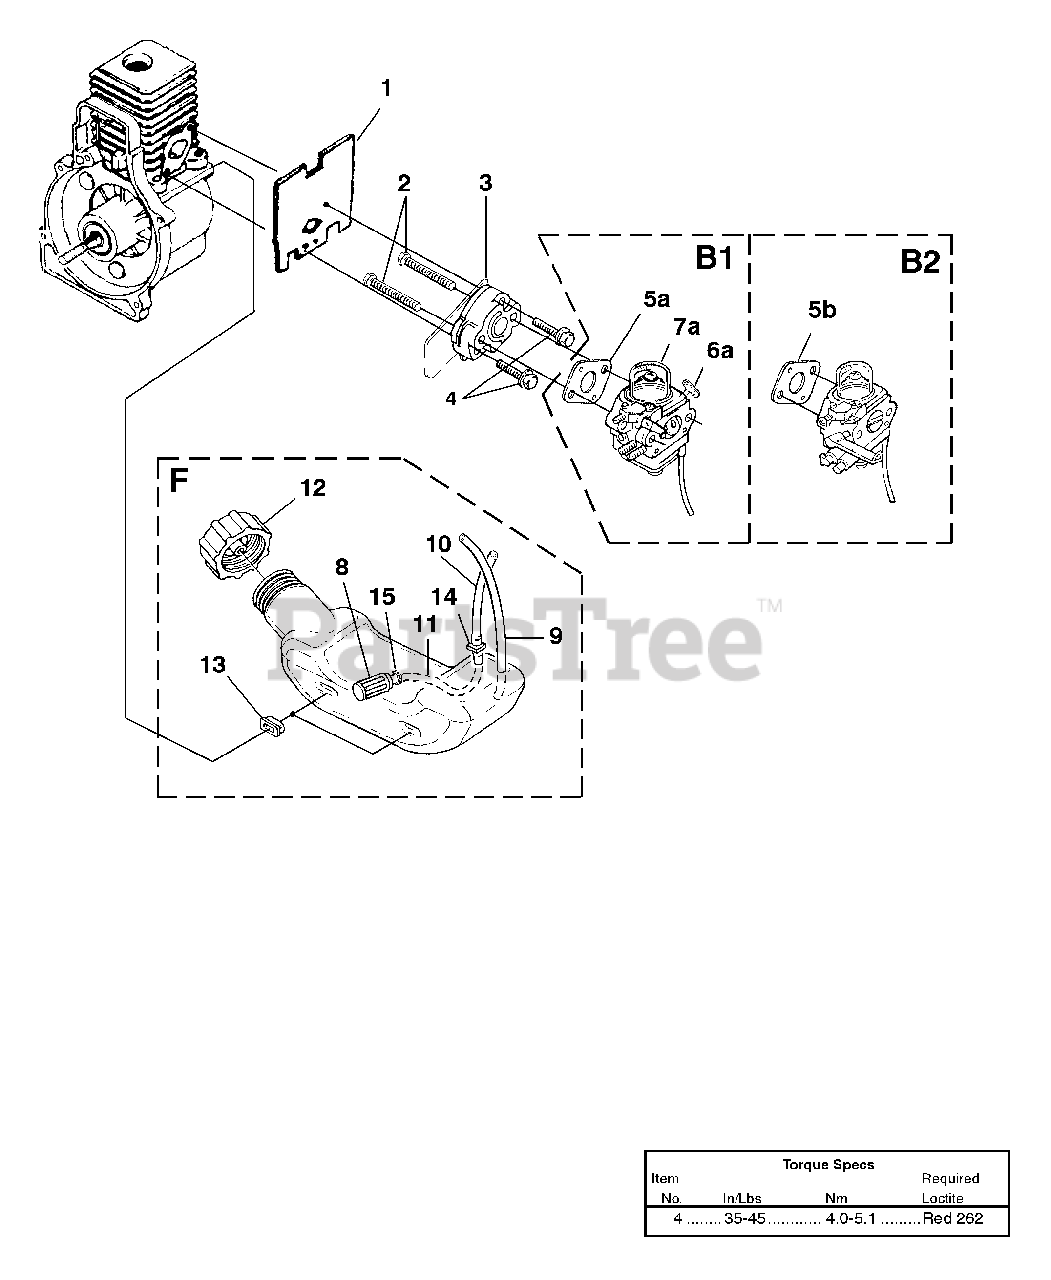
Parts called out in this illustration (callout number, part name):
1	GASKET-Heat Dam
2	SCREW-Machine (10-24 X 2 1/4")
3	HEAT DAM
4	SCREW-Sems (10-24 X 1")
8	FILTER-Fuel
9	TUBING-Rubber
10	TUBING-Rubber
11	TUBING-Rubber
12	FUEL CAP
13	BUMPER-Rubber
14	FITTING-Inline
15	CLAMP
B1	CARBURETOR KIT
B2	CARBURETOR KIT
F	FUEL TANK ASSY.
